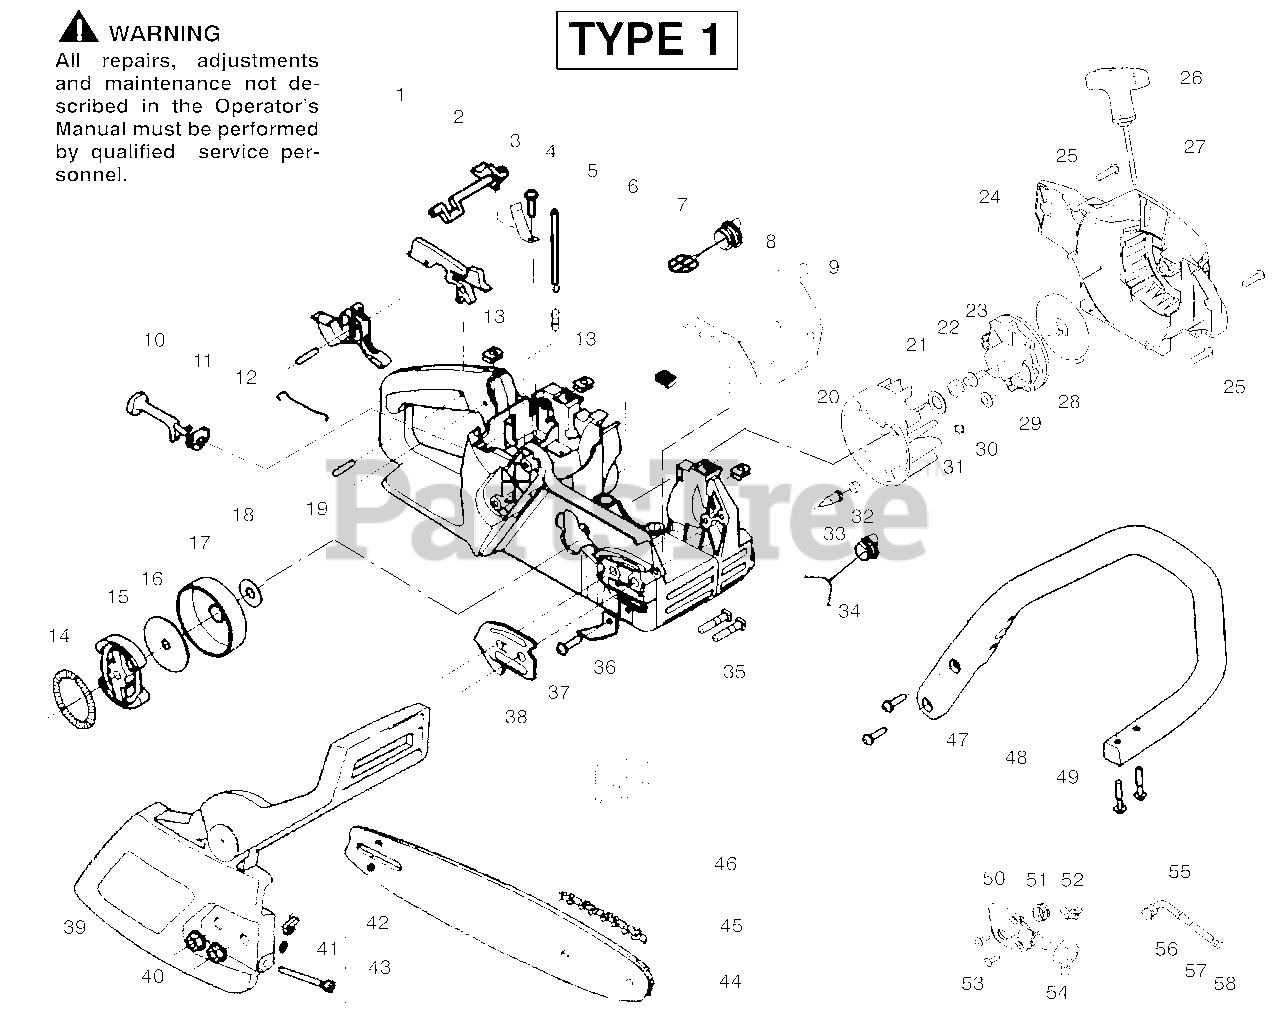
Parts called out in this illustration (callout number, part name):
1	Kit-Trigger & Lockout
2	Lever-Switch
3	Spring-Switch
5	Kit-Fuel Line
6	Fitting - Fuel Line
7	Assy-Fuel Cap
8	Clip - "U"
9	Shield - Heat
10	Lever-Choke
11	Grommet-Choke Lever
12	Wire-Throttle
13	Nut-Speed
14	Spring - Clutch
15	Assy.-Clutch
16	Washer-Clutch
17	Assy-Drum W/Brg.
18	Washer - Thrust
19	Kit - Chassis Assy.
20	Assy-Flywheel
21	Washer-Flywheel
22	Nut-Flywheel
24	Fan Housing
26	Handle-Starter
27	Kit-Rope
28	Spring-Starter
29	Starter Pulley
31	Spring - Starter Dog
32	Plug - Bronze Vent
33	Check Valve
34	Assy-Oil Cap
35	Bolt - Bar
36	Chain Catcher
38	Plate-Bar Mounting
39	Assy.-Chain Brake
40	Nut-Bar Mounting
41	Retainer-Bar Adjust
42	Pin-Bar Adjust
43	Kit-Bar Adjust
45	Chain-18"
48	Front Handle
50	Kit-Oil Pump
51	Gear-Worm Spring
52	Elbow-Oil Pickup
54	Seal Block
55	Assy-Oil-Pickup
56	Oiler Pickup
57	Oil Filter
58	Plug-Oil Filter
